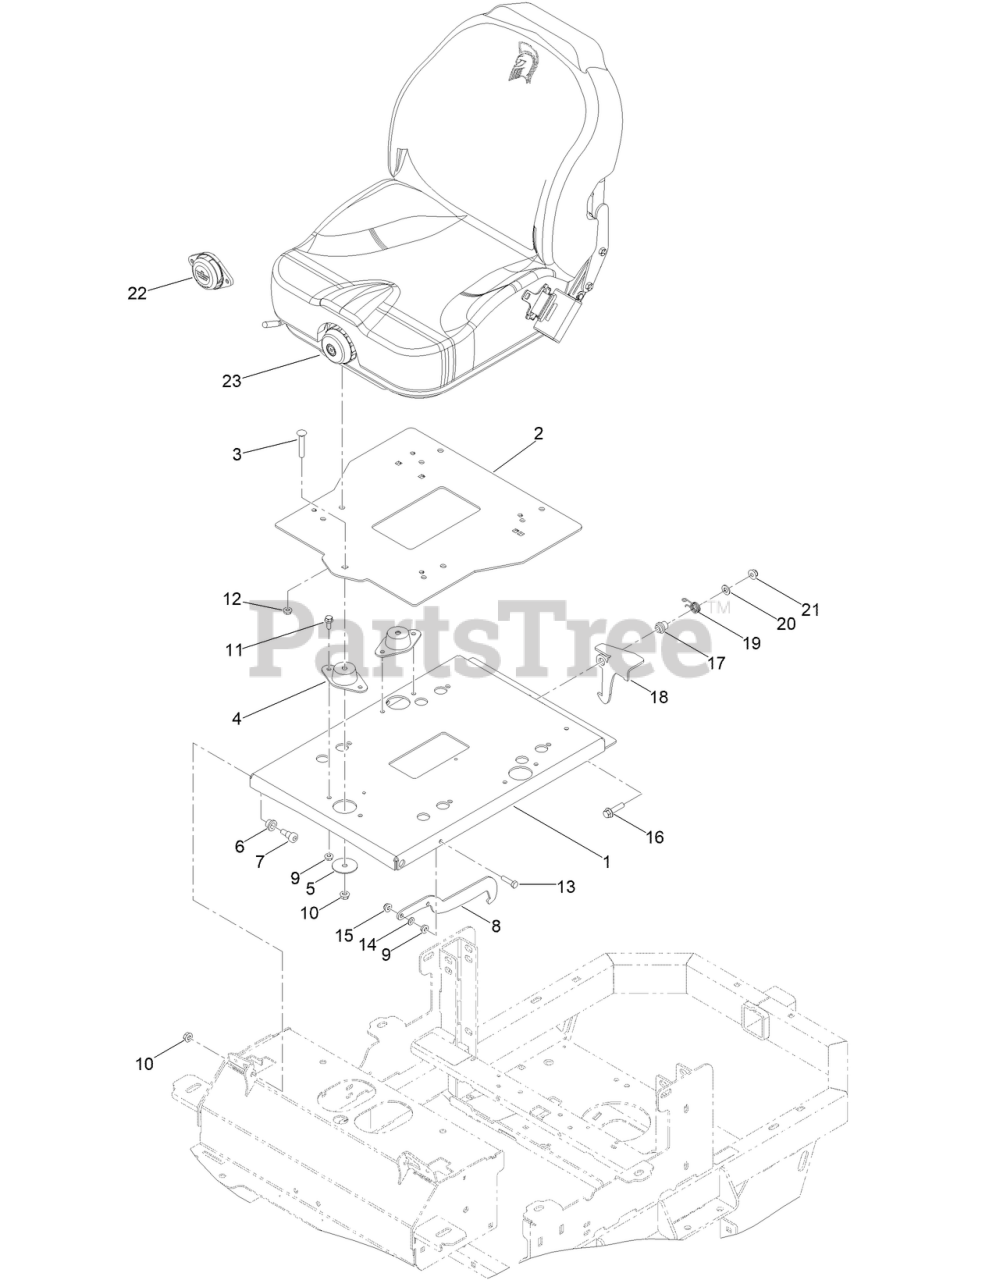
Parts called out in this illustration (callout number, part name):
1	360 SEAT BASE PLATE SAFTY DECAL ASM-05
2	2019 UPGRADE SEAT PLATE
3	SCREW-CARR
4	FLOATING SEAT DAMPER-STIFFER
5	3/8 X 2IN OD FENDER WASHER YZ
6	1/2IN ID X 5/8IN OD X 1/2IN FLANGE BUSH
7	1/2 X 1/2 SOCKET SHOULDER BOLT ZC YELLOW
8	MWR SEAT LATCH HOOK BLACK
11	SCREW-HHF
12	5/16-18 NYLON INSERT FLANGE L/NUT ZC
13	SCREW-HH
14	.312IDX.625ODX.062 THK THRUST BRG OI BRZ
15	NUT-HF, NI
16	SCREW-HHF
17	BUSHING-LATCH, SEAT
18	BRACKET-LATCH
19	SPRING-TORSION, LATCH
20	WASHER-FLAT
21	NUT-HF, NI
22	MWR SEAT SWITCH
23	SEAT-SUSP
